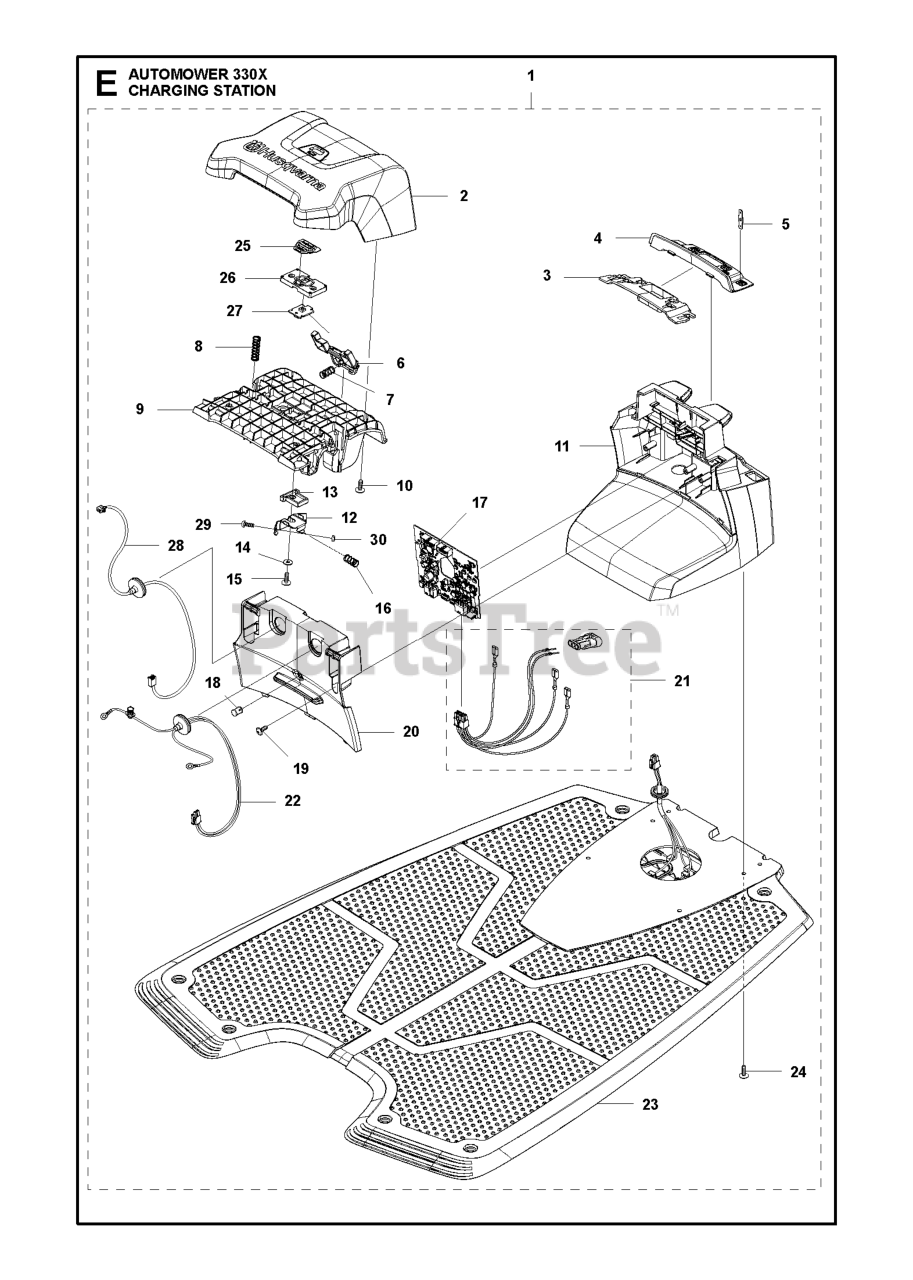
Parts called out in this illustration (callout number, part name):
1	CHARGING STATION AUTO MOWER 33
2	CAP CHARGING STATION WITHOUT H
3	HOLDER CHARGING STATION
4	PAN CHARGING STATION 320, ONE
5	TERMINAL TERMINAL CHARGING STA
6	BUTTON CHARGING STATION, RELEA
7	SPRING STOP BUTTON
8	SPRING SPRING CAP
10	SCREW 14MM
13	DISTANCE CHARGING STATION
15	SCREW 14MM
16	SPRING SPRING CAP
18	LENS
19	SCREW 14MM
20	LID CHARGING STATION 330, TWO
23	CHARGING PLATE
24	SCREW 14MM
28	LOOM HOME BUTTON
29	SCREW ITXPANM M4X12 8.8 ZP-BC
30	NUT M4
